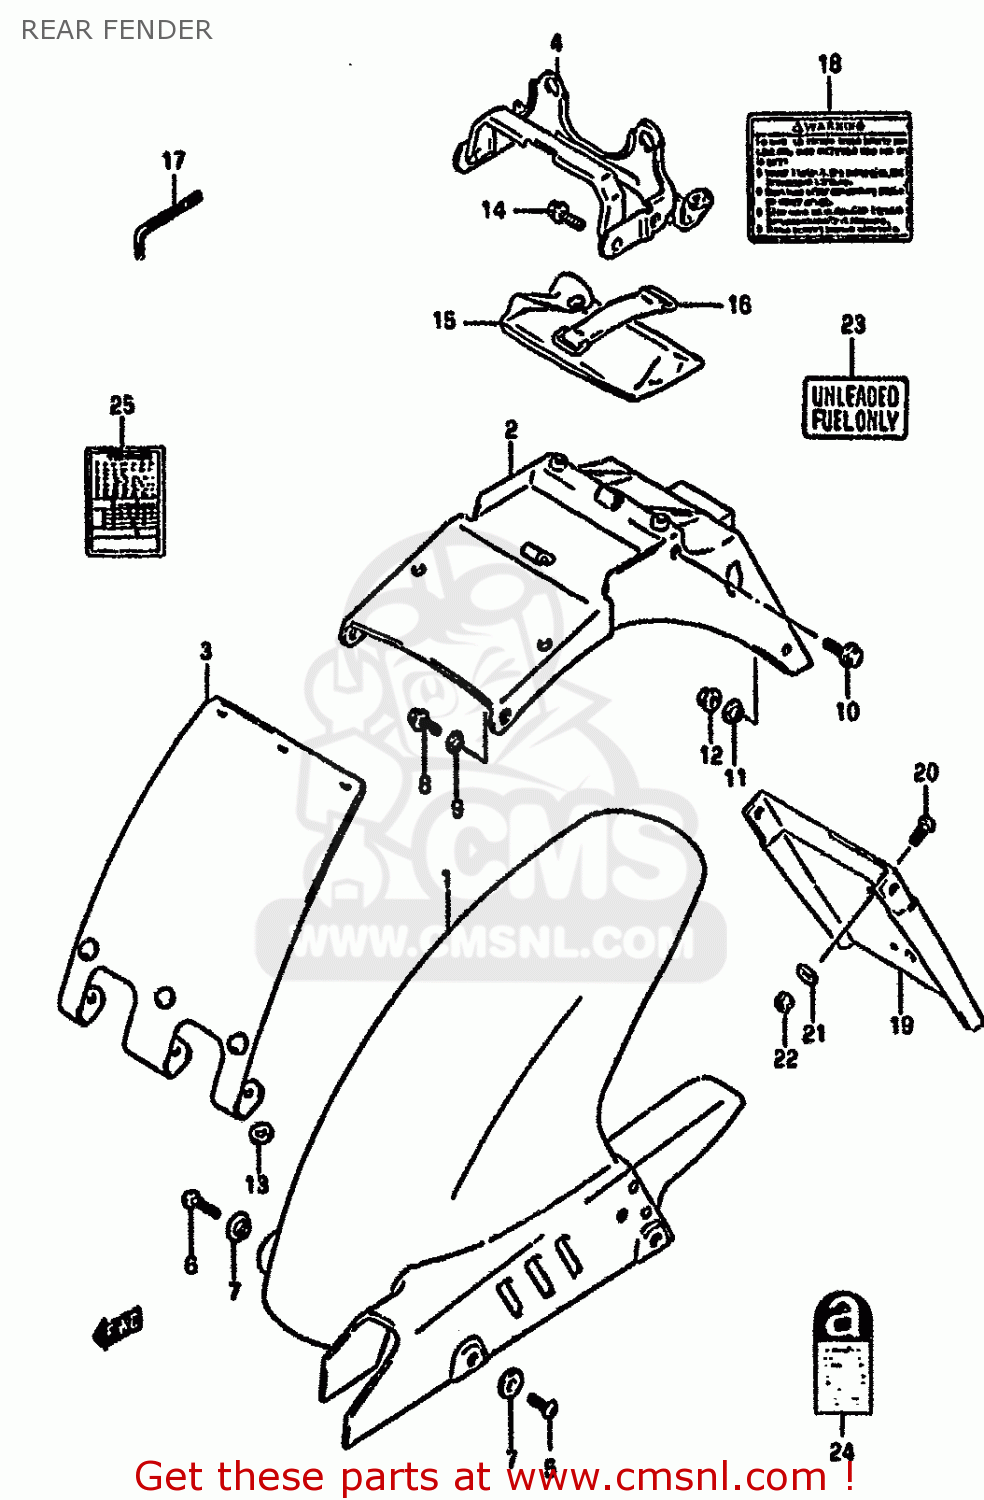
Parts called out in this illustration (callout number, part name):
1	FENDER,REAR
2	BODY,RR FENDER UPR
3	MUDGUARD ASSY,RR FENDER
4	BRACKET,FRAME COVER
5	SCREW 6X12
6	SCREW
7	WASHER
8	BOLT 6X16
9	WASHER
10	BOLT 8X30
11	WASHER
12	NUT
13	WASHER
14	BOLT 6X16
15	TOOL SET
16	BAND
17	SPANNER,HEXAGON(4)
18	LABEL, WARNING SAFETY
19	EXTENSION,REAR FENDER
20	SCREW
21	WASHER(6.5X16X1.2)
22	NUT
23	LABEL,CAUTION
24	LABEL,ASBESTOS WARNING
25	LABEL,TIRE AIR PRESSURE
